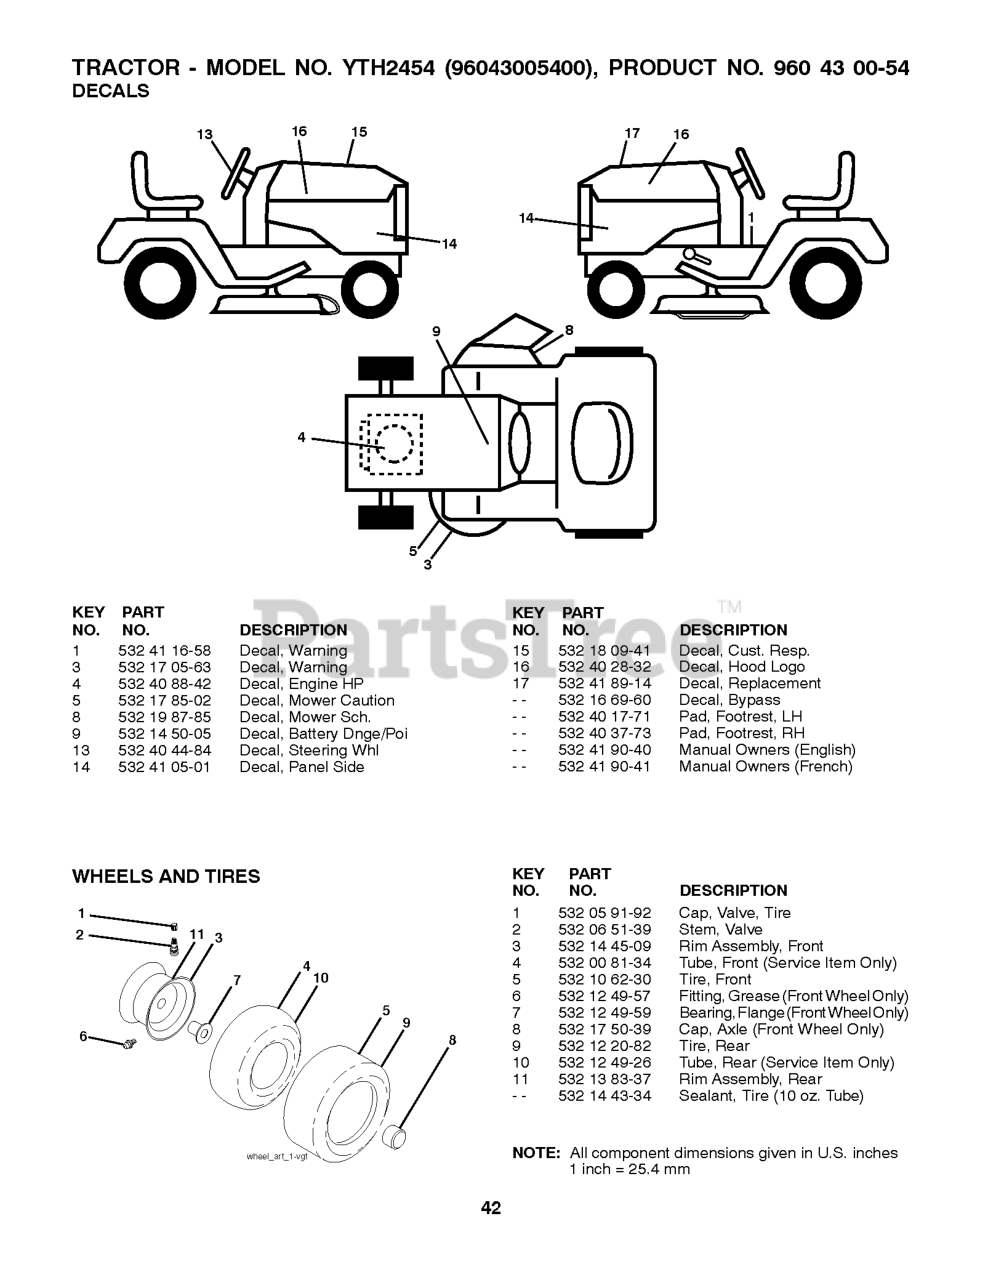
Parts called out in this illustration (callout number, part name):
1	DECAL.FENDER.WARNING.ENG
3	DECAL.WARN.KEEP.HAND.AWAY
4	DECAL, ENGINE, HP
5	DECAL CLUTCH/BRAKE
8	DECAL.MOWER.SCH.48/54
9	DECAL BTRY SYMBOLS
13	DECAL.WHEEL.STRG.LGN.H
14	DECAL PANEL
15	DECAL HOOD CUST. RESP.
16	DECAL.HOOD.NAMELOGO.HUSQ
17	DECAL.RPL.BSM44.INTK.K46/46TLW
